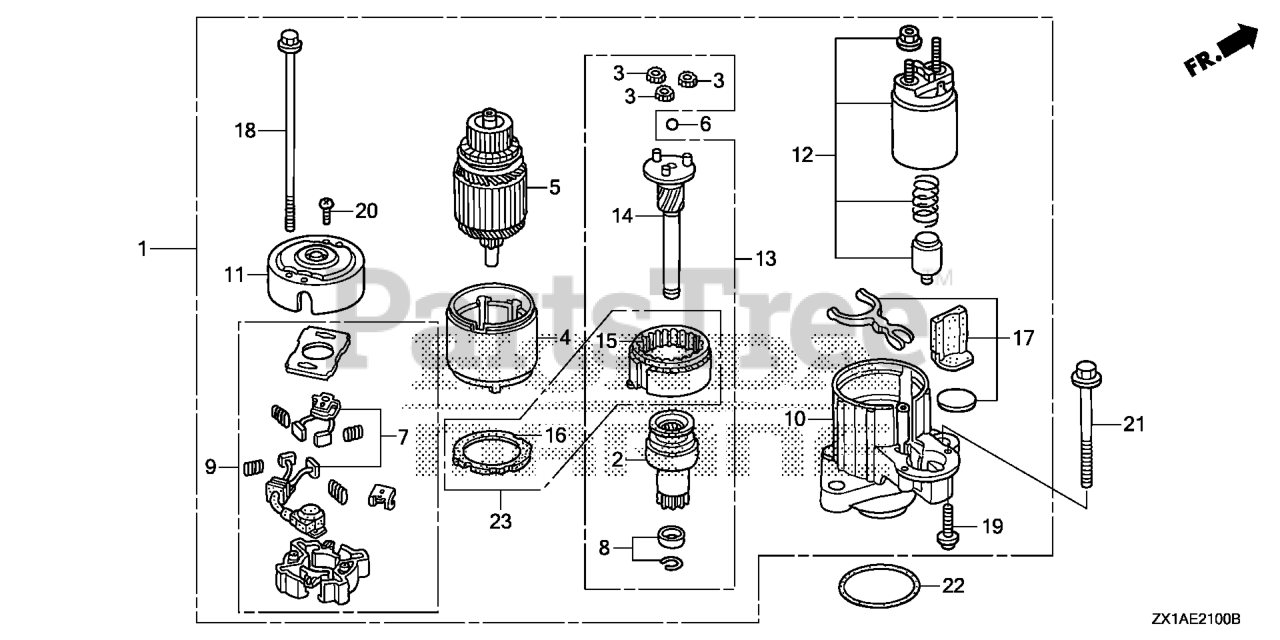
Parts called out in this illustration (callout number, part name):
1	STARTER MOTOR ASSY.
2	CLUTCH, OVERRUNNING
3	GEAR ASSY., PLANETARY
6	BALL, STEEL
7	BRUSH SET
8	STOPPER SET, SLEEVE
9	HOLDER, BRUSH
10	BRACKET, FR.
11	BRACKET, RR.
12	SWITCH ASSY., MAGNET
13	SHAFT ASSY., CLUTCH
14	SHAFT ASSY., GEAR
15	GEAR ASSY. (INNER)
16	GASKET
18	BOLT A, THROUGH
19	SCREW, PAN (6X22)
19	SCREW, PAN (6X22) (SPECIAL)
20	SCREW, PAN (5X8)
21	BOLT, FLANGE (10X90)
22	O-RING (59.4X3.1)
23	GEAR ASSY. (INNER)
